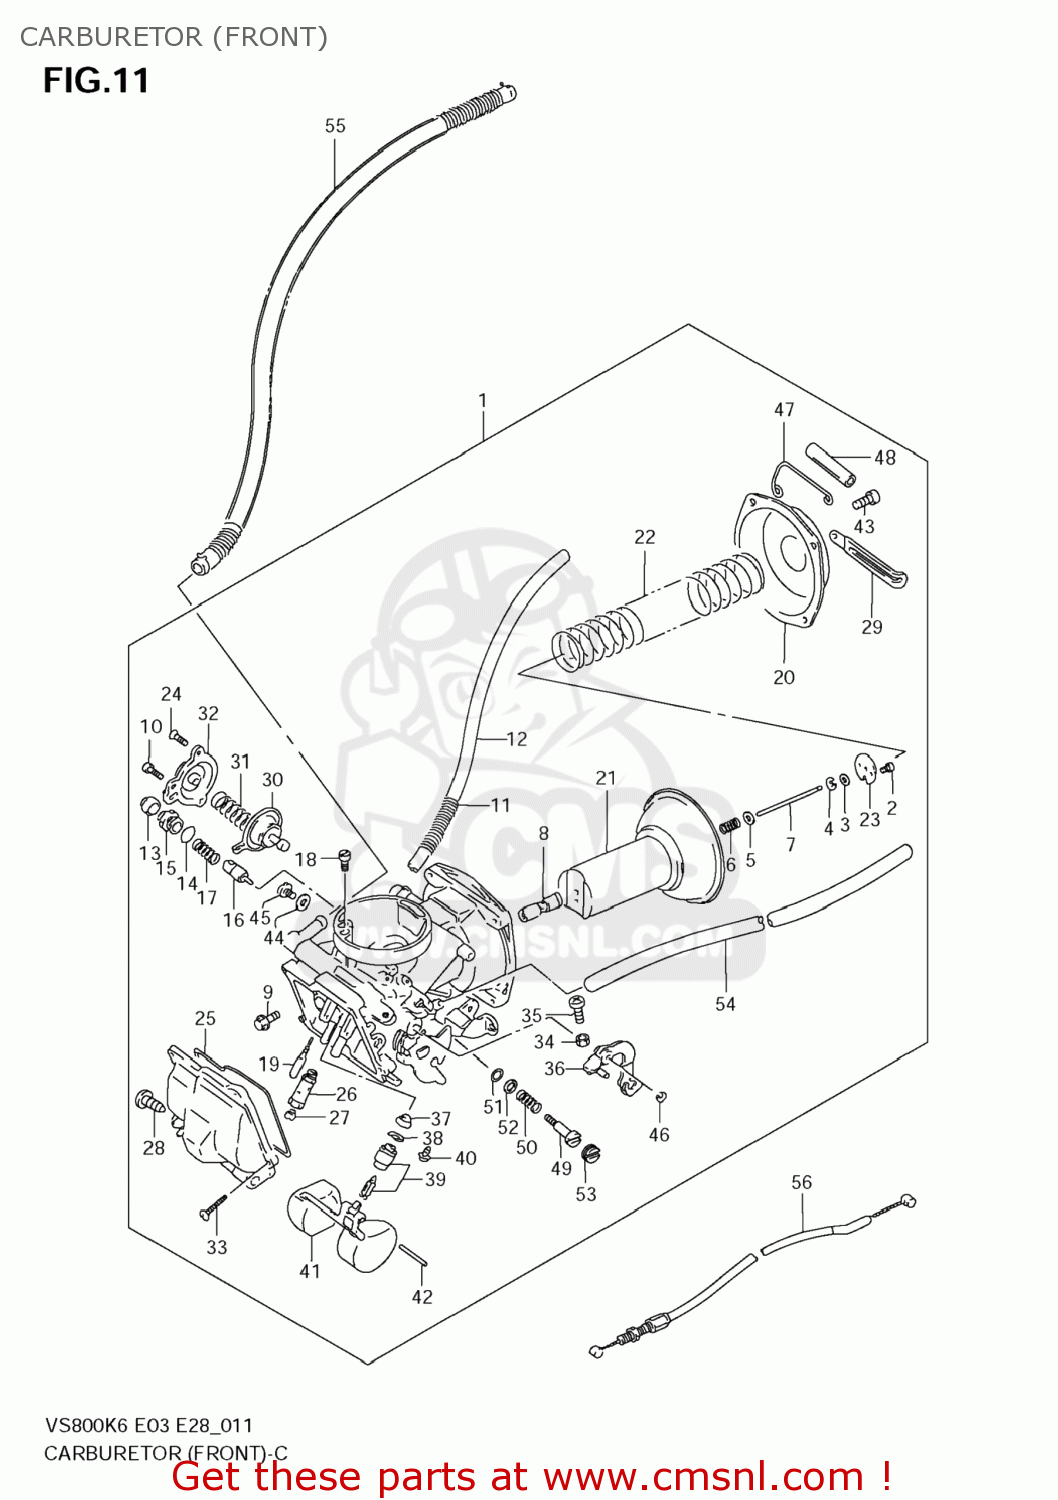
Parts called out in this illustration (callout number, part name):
1	CARBURETOR ASSY,FR
2	SCREW
3	RING
4	CLIP
5	WASHER
6	SPRING
7	NEEDLE,JET
8	JET,NEEDLE(P-2M)
9	SCREW
10	SCREW
11	SPRING
12	HOSE(5X8.2X600)
13	CAP
14	O RING
15	HOLDER,GUIDE
16	PLUNGER,STARTER
17	SPRING
18	JET,AIR(65)
19	JET,PILOT(40)
20	COVER,DIAPHRAGM
21	DIAPHRAGM,CARBURETOR
22	SPRING,DIAPHRAGM
23	PLATE
24	SCREW,UPPER
25	O RING,FLOAT CHAMBER
26	HOLDER,MAIN JET
27	JET,MAIN(127.5)
28	SCREW,DRAIN
29	CLAMP(L:65)
30	DIAPHRAGM ASSY
31	SPRING
32	COVER
33	SCREW
34	NUT
35	SCREW
36	LEVER,ASSY
37	FILTER
38	O RING,NEEDLE VALVE SEAT
39	VALVE ASSY,NEEDLE
40	SCREW
41	FLOAT
42	PIN,FLOAT
43	SCREW
44	GASKET,DRAIN PLUG (NAS)
45	SCREW
46	E RING
47	CLIP
48	HOSE(6X10X600)
49	SCREW,PILOT
50	SPRING
51	O RING,PILOT AIR SCREW
52	WASHER
53	PLUG
54	HOSE ASSY
55	HOSE ASSY
56	CABLE,IDLE SYNCRO
